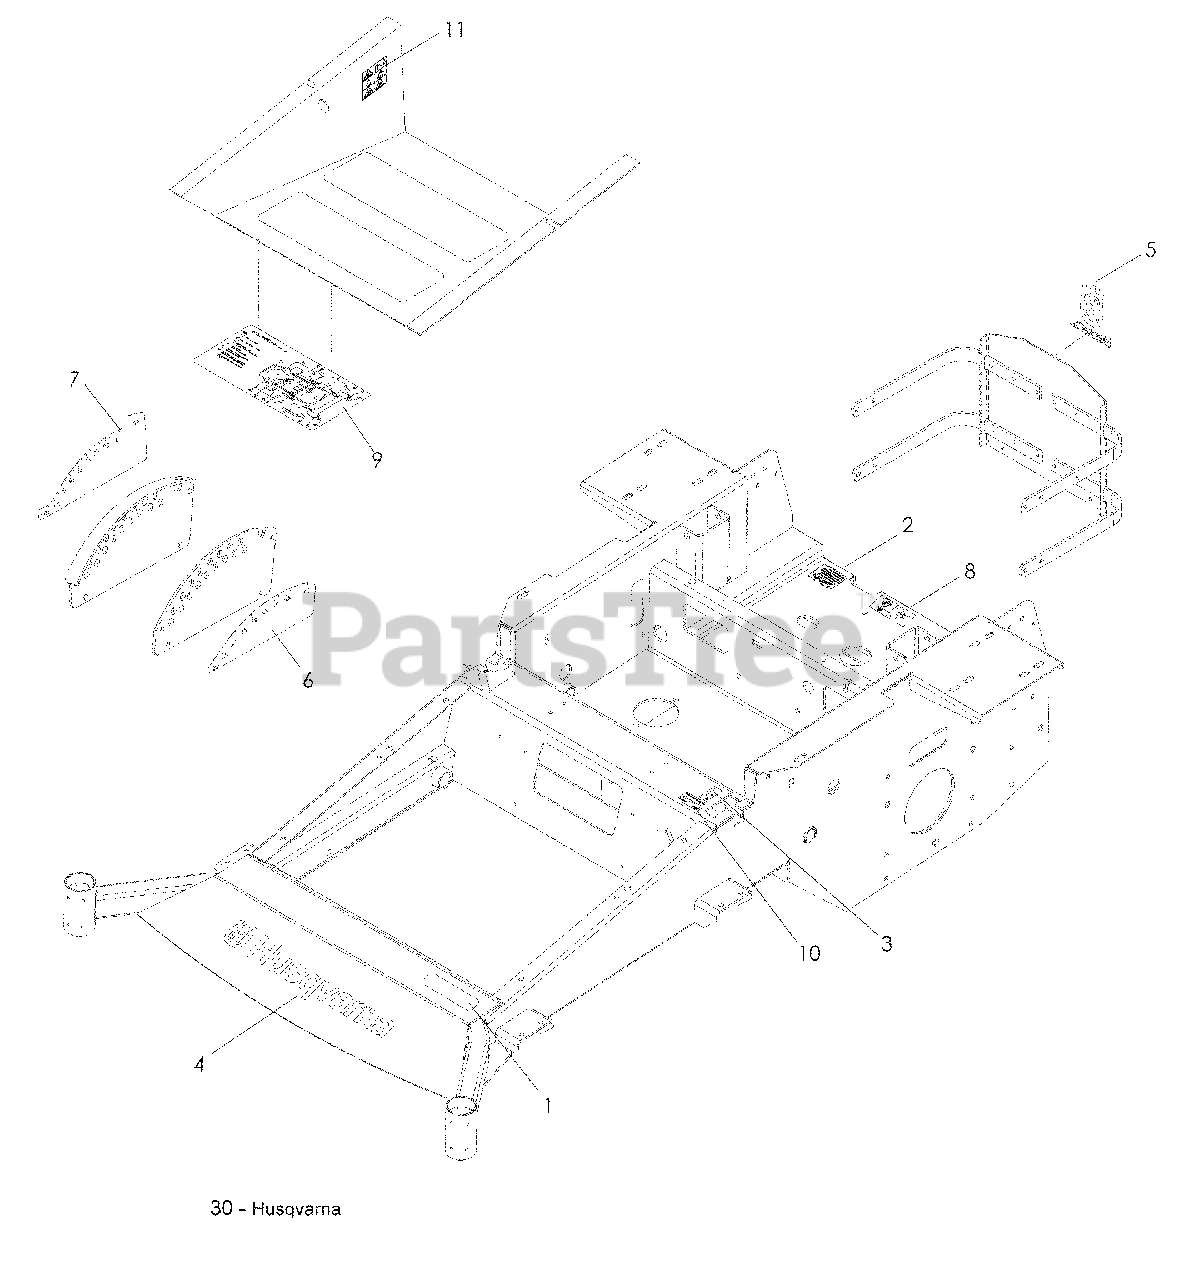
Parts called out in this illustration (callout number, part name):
1	DECAL, LZ5225
2	DECAL, PROP 65
3	DECAL, MOTION CONTROL
4	DECAL, HUSQVARNA
5	DECAL, CROWN
6	DECAL, HEIGHT INDICATOR
7	DECAL, HEIGHT INDICATOR
8	DECAL, DNGR BELT DRIVE
9	DECAL, SERVICE
10	DECAL, TRACKING
11	DECAL, WARNING
